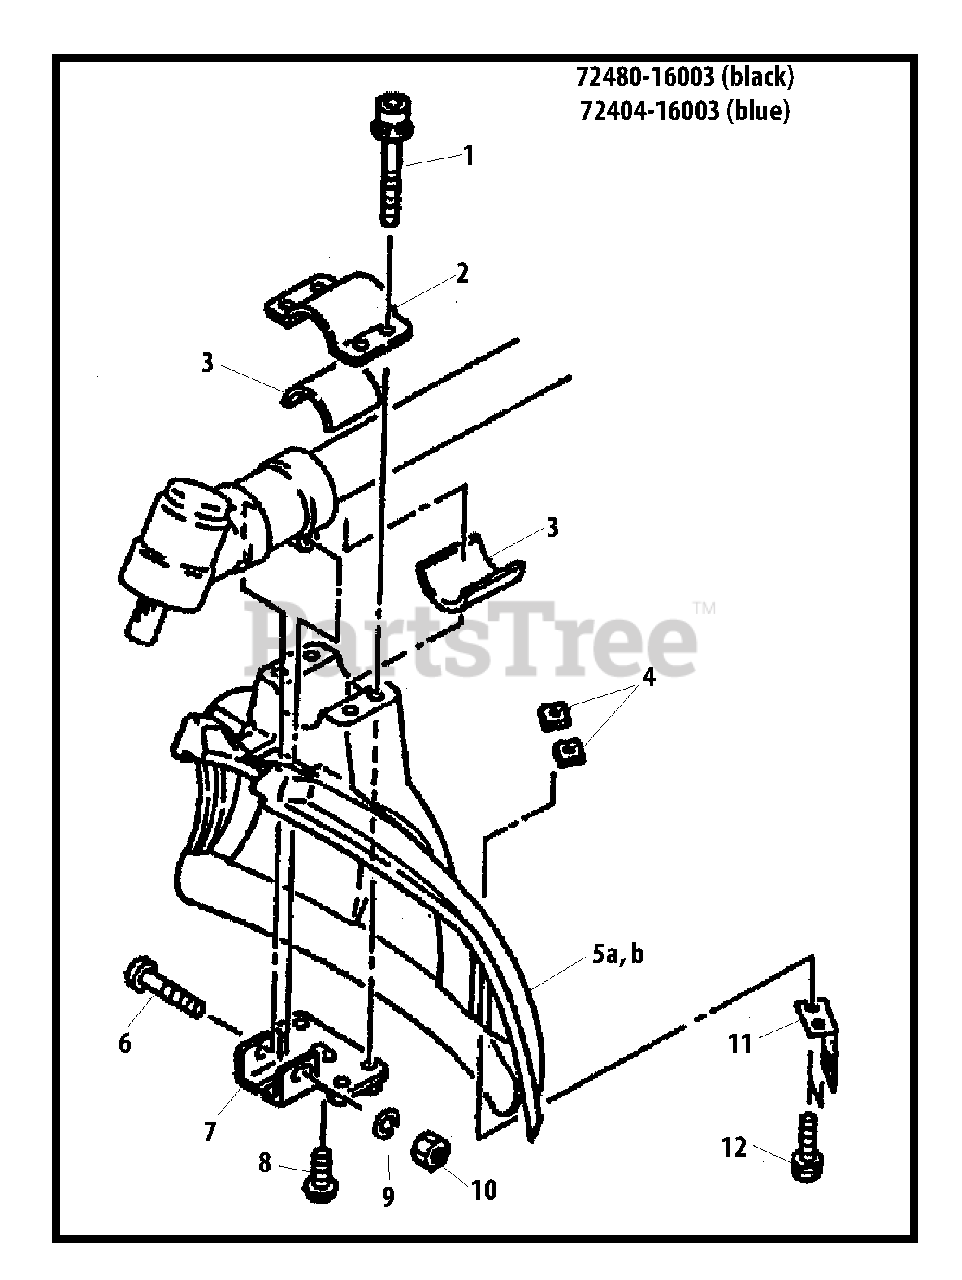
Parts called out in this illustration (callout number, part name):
1	BOLT M5×45
2	CLAMP, UPPER
3	SPACER
4	NUT M5
5A	SHIELD, DEBRIS
5B	SHIELD, DEBRIS - BLUE
6	BOLT M5×35
7	PLATE, SHIELD MOUNTING
8	SCREW HILO 4×10
9	WASHER 5 MM
10	NUT M5
11	CUTTER
12	BOLT M5×16
72404-16003	DEBRIS SHIELD KIT - BLUE
72480-16003	DEBRIS SHIELD ASSY
